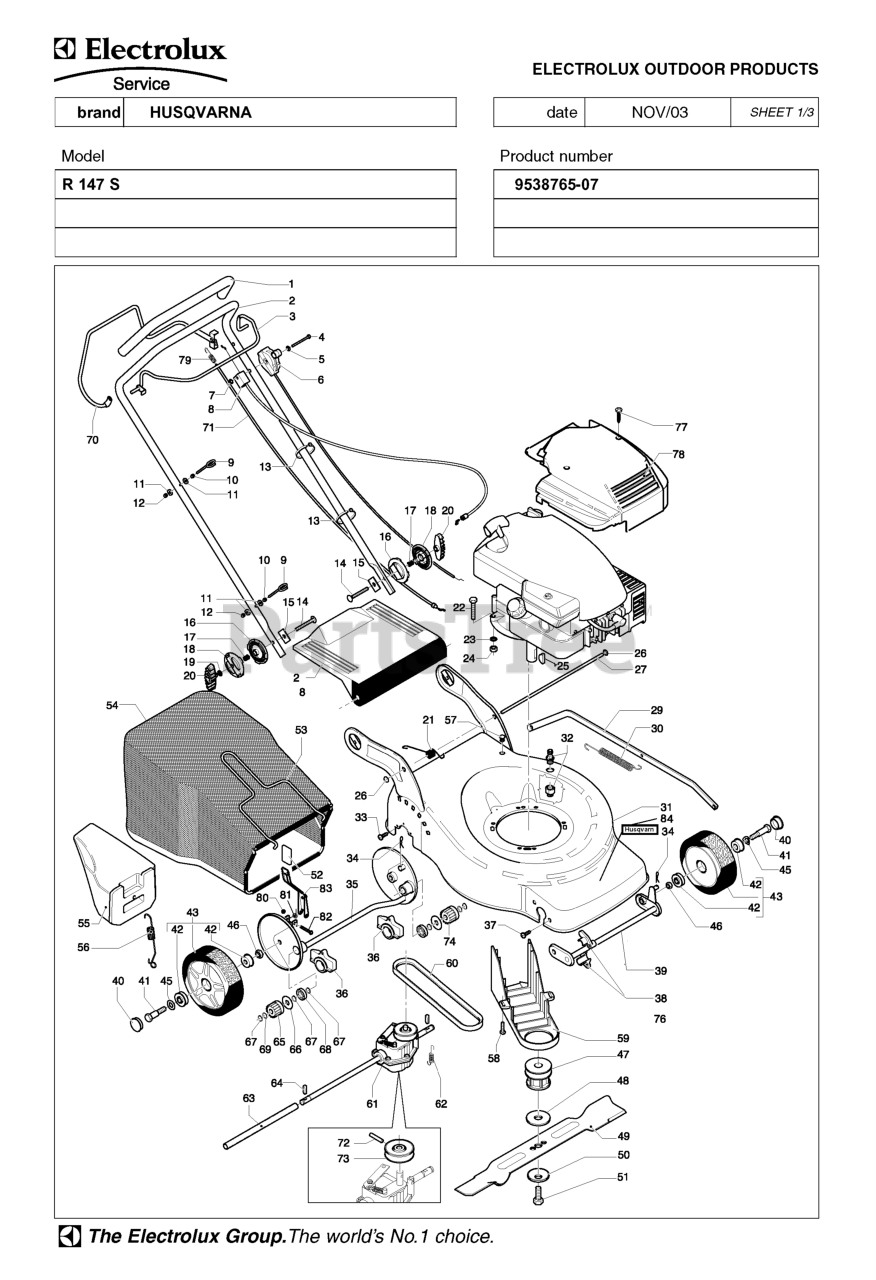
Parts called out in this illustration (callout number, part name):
34	Pins
58	Screws
67	Washers
